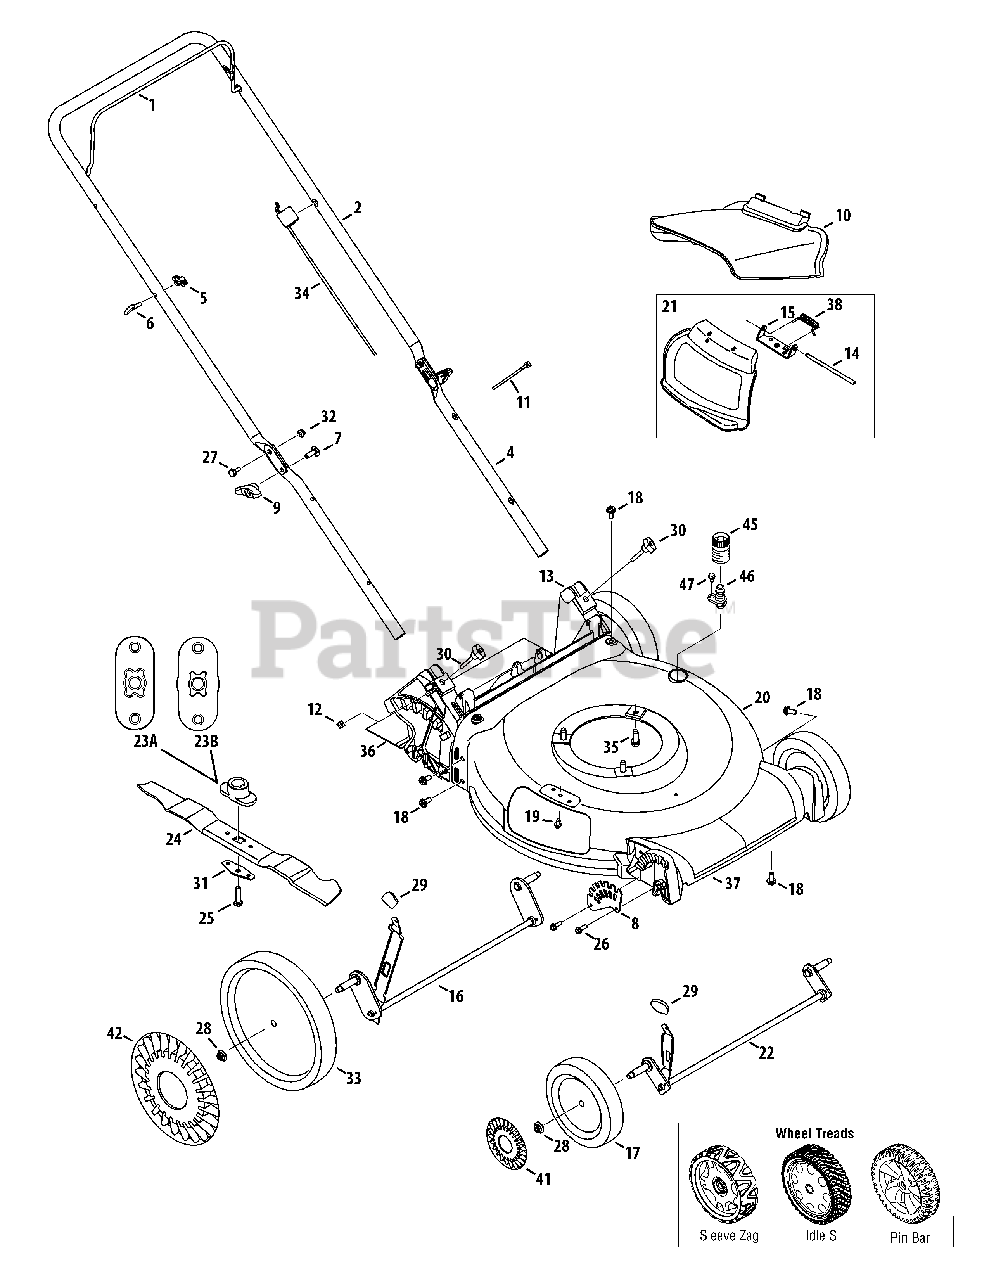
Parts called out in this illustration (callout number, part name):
1	Blade Control Handle - Black
2	Upper Handle - Black (non adjustable)
2	Upper Handle - Black (adjustable)
4	Lower Handle
5	Knob 1/4-20
6	Rope Guide Bolt
7	Carriage Bolt 5/16-18
8	Front Height Adjustment Plate
9	Wing Knob 5/16-18 Red
9	Wing Knob 5/16-18 Black
10	Chute Deflector
10	Chute Deflector (w/clip)
11	Cable Tie
12	Sq. Nut 1/4-20
13	Rear Baffle
14	Hinge Pin
15	Chute Deflector Bracket
16	Rear Axle Ass'y - 11" wheel
17	Wheel Ass'y 7 x 2.0 Sleeve Zag Black
18	Hex Hd. Cap Screw. 5/16-14 x .75
19	Sems TT Screw. 1/4-20 x .50
21	Hinged Mulch Plug Ass'y (Incl. ref. no. 15, 38 & 14)
22	Front Axle Ass'y - 7 " wheel
23A	Blade Adapter (#6 X 1.19 w/star)
23B	Blade Adapter (25 mm x 1.19)
24	21" Mulching Blade
25	Hex Bolt 3/8-24 x 1.5" Lg. (Gr 8)
26	Screw, 1/4-15 x .750
27	Shoulder Screw .375 x .126 x 1/4-20
28	Flange Locknut 3/8-16 Gr. F Nylon
29	Knob (Black)
29	Knob (Red)
30	Knob 1/4-20 x 1.725 Black
30	Knob 1/4-20 x 1.725 Red
31	Blade Bell Support
32	Flanged Lock Nut 1/4-20 Gr. F Nylon
33	Wheel Ass'y 11 x 2 Sleeve Zag Black
34	Control Cable, 158 cc B&S
35	Hex Wash HD Tap Screw 3/8-16 x .88
36	Trailing Shield 4.54 x 17.37
37	Front Axle Cover
38	Torsion Spring
41	Hub Cap (11")
42	Hub Cap (7")
45	Water Nozzle Adapter
46	Deck Water Nozzle
47	Shoulder Screw 1/4-20 x .50
